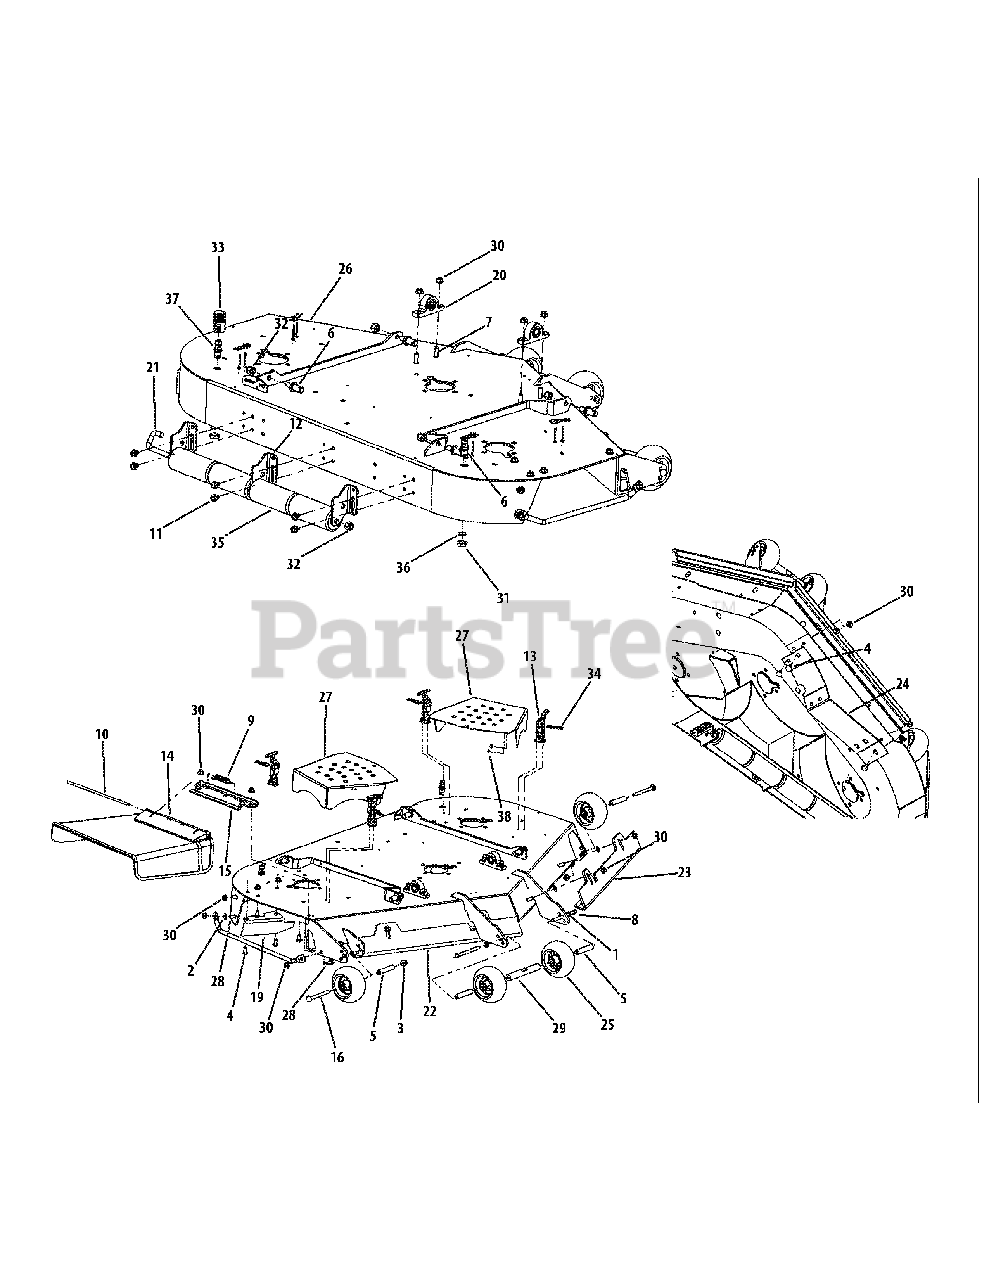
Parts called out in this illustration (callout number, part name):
1	Lock Washer, 3/8
2	Flat Washer, 3/8
3	Hex Nut, 3/8-16 Flange Lock
4	Carriage Bolt, 3/8-16 x .75 Lg.
5	Wheel Spacer
6	Pin, 5/8 Dia. x 1.2 Lg.
7	Carriage Screw, 3/8-16 x 1.25
8	Hex Cap Screw, 3/8-16 x 4.50
9	Spring Torsion, 0.4 ID x 2.16 LG
10	Defllector Chute Rod
11	Hex Index Washer Screw, 3/8-16, .5
12	Roller Mount Bracket
13	T-Handle Draw Latch
14	Deflector Chute
15	Deflector Chute Bracket
16	Carriage Bolt, 3/8-16 x 4.00
17	Push Retainer
18	Finger Guard
20	Pillow Block
21	J-Hook w/ Threaded Roller
22	Right Hand Front Adjustment Skirt
23	Left Hand Front Adjustment Skirt
24	Baffle, 54" Adjustment
25	Complete Wheel, 5.00 Dia.
26	54" Deck Assembly
27	Deck Belt Cover
28	Carriage Bolt, 3/8-16 x 1
29	Ball Wheel Mounting Shaft
30	Lock Nut, Nylon Insert, 3/8-16
31	Hex Nut, M16-1.5
32	Lock Nut, Nylon Insert, 1/2-13
33	Water Nozzle Adaptor
34	Phillips Head Screw, 10-32
35	Front Roller
36	Lock Washer, 17 x 23.8 x 1.95
37	Deck Water Nozzle
38	Lock Nut, Nylon Insert, 10-32
